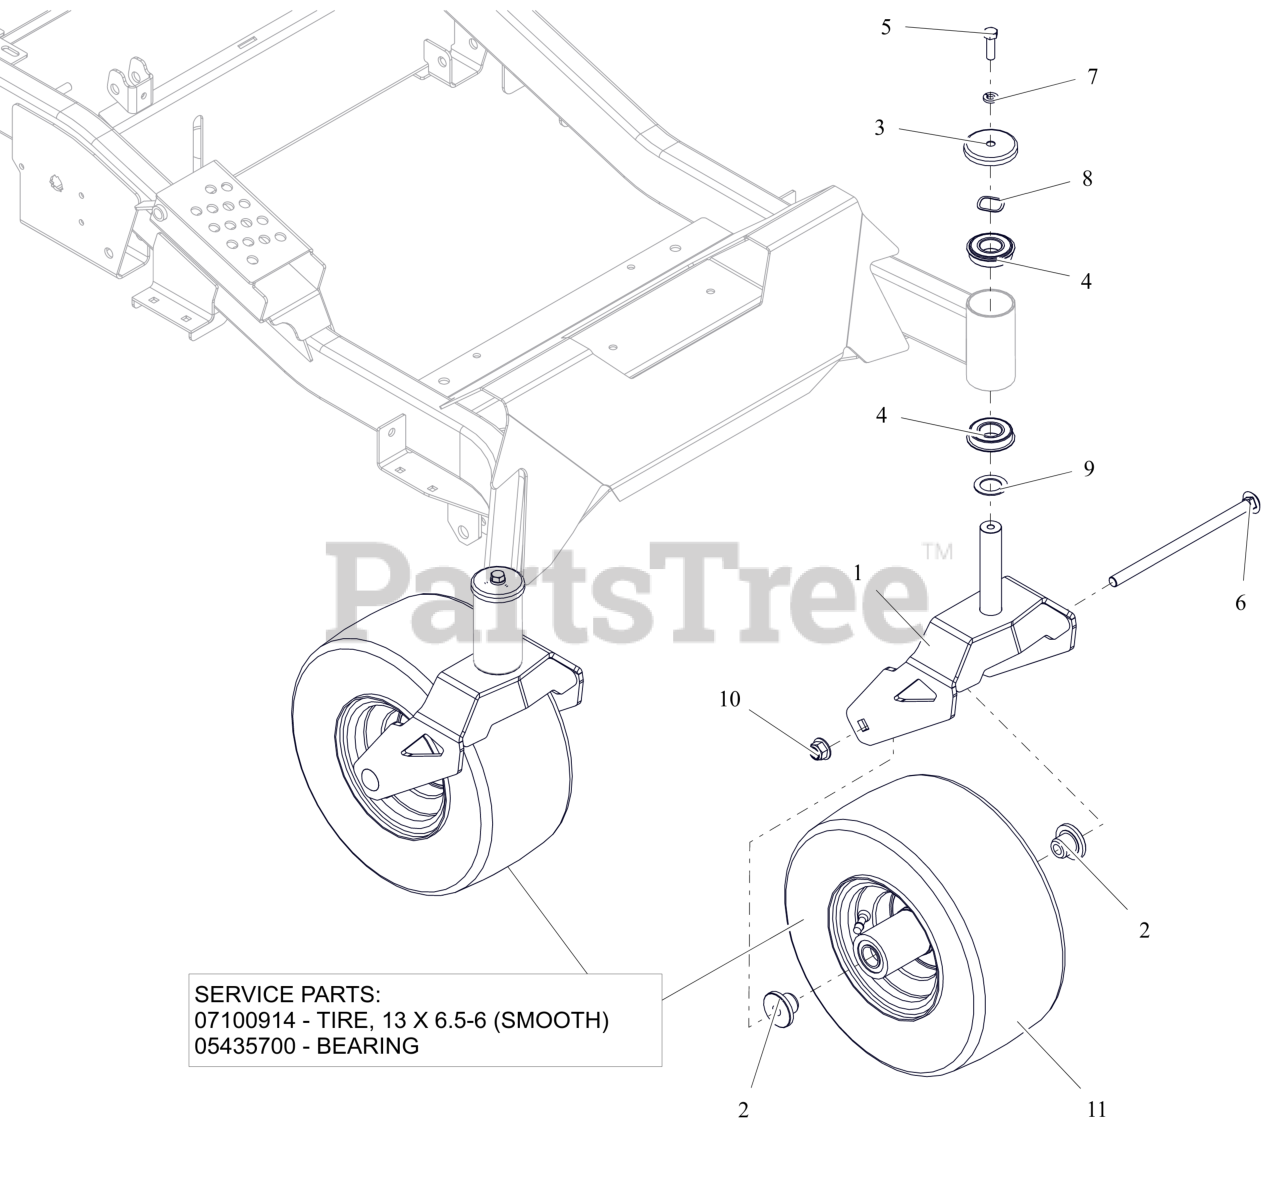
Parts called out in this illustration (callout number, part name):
1	WLDMT, CASTER FORK-HD (ORANGE)
2	SPACER, FRONT WHEEL
3	SHIELD, AXLE BEARING
4	BEARING, BALL -2.000 OD X 1.000 ID X .5625 W/RING
5	BLT, HEX .38-16X1.25 G5 ZCC
6	BLT, RHSN .50-13X9.00 G5 ZCC
7	WSHR, LK-HVY .375X.115 ZCC
8	WSHR-WAVE 1.0X1.25X.028 .145FH
9	WSHR-HRD-THRS 1.007X1.542X.062
10	NUT,NYL-FLG .50-13 GF ZCC
11	ASM, WHL/TIRE 13X6.50-6
11	TIRE, 13X6.50-6 SMOOTH
11	BRG, 25MM ID X 52MM OD X 15MM
